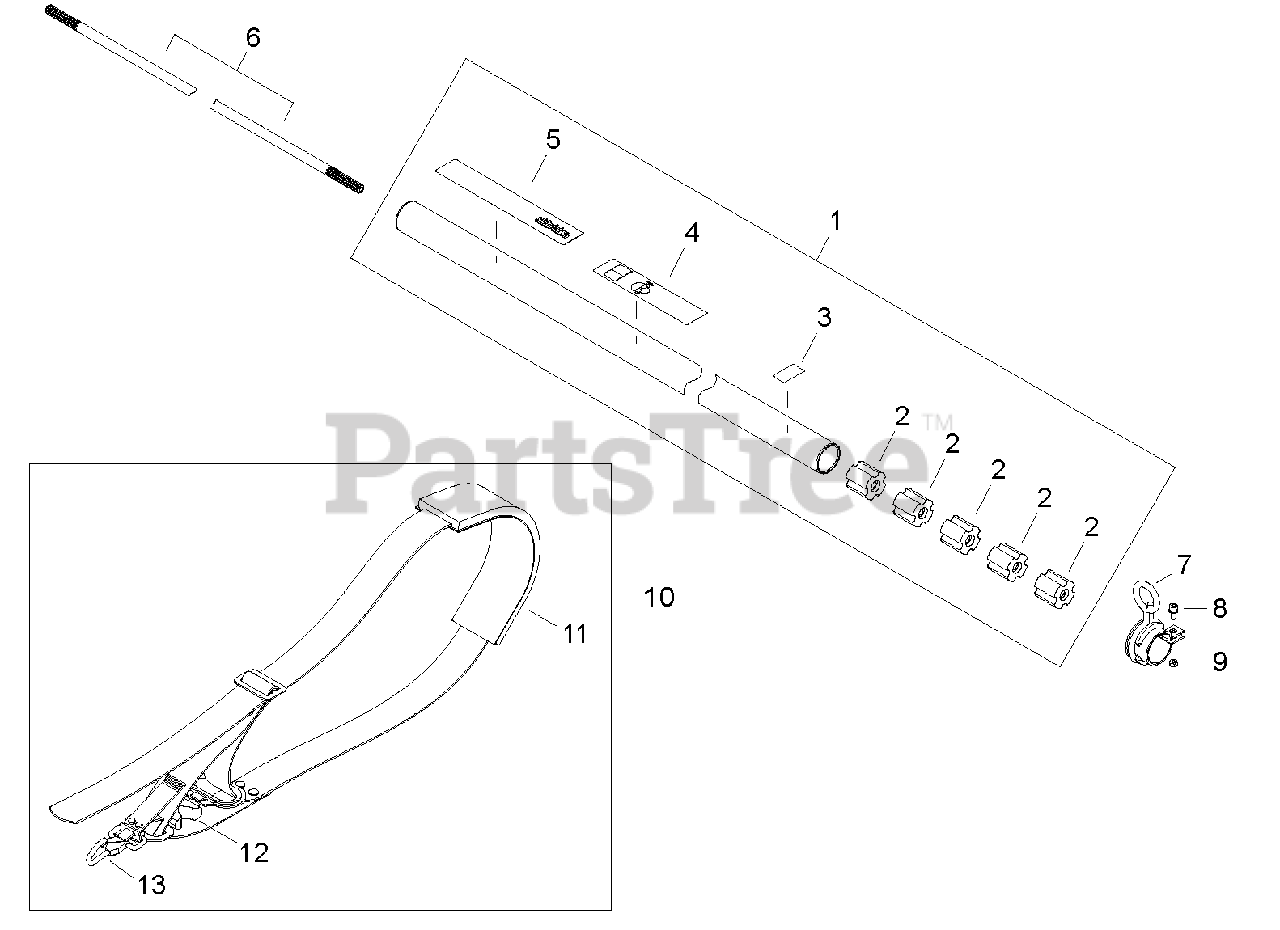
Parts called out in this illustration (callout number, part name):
1	MAIN PIPE ASSY
2	BUSHING
3	LABEL, HANDLE
4	LABEL, CAUTION (BLADE CAPABLE)
5	LABEL, SHINDAIWA PROFESSIONAL
6	MAINSHAFT
7	HANGER, SWIVEL
8	BOLT M5×12
9	NUT M5
10	HARNESS ASSY
11	PAD, SHOULDER
13	HOOK, SNAP
